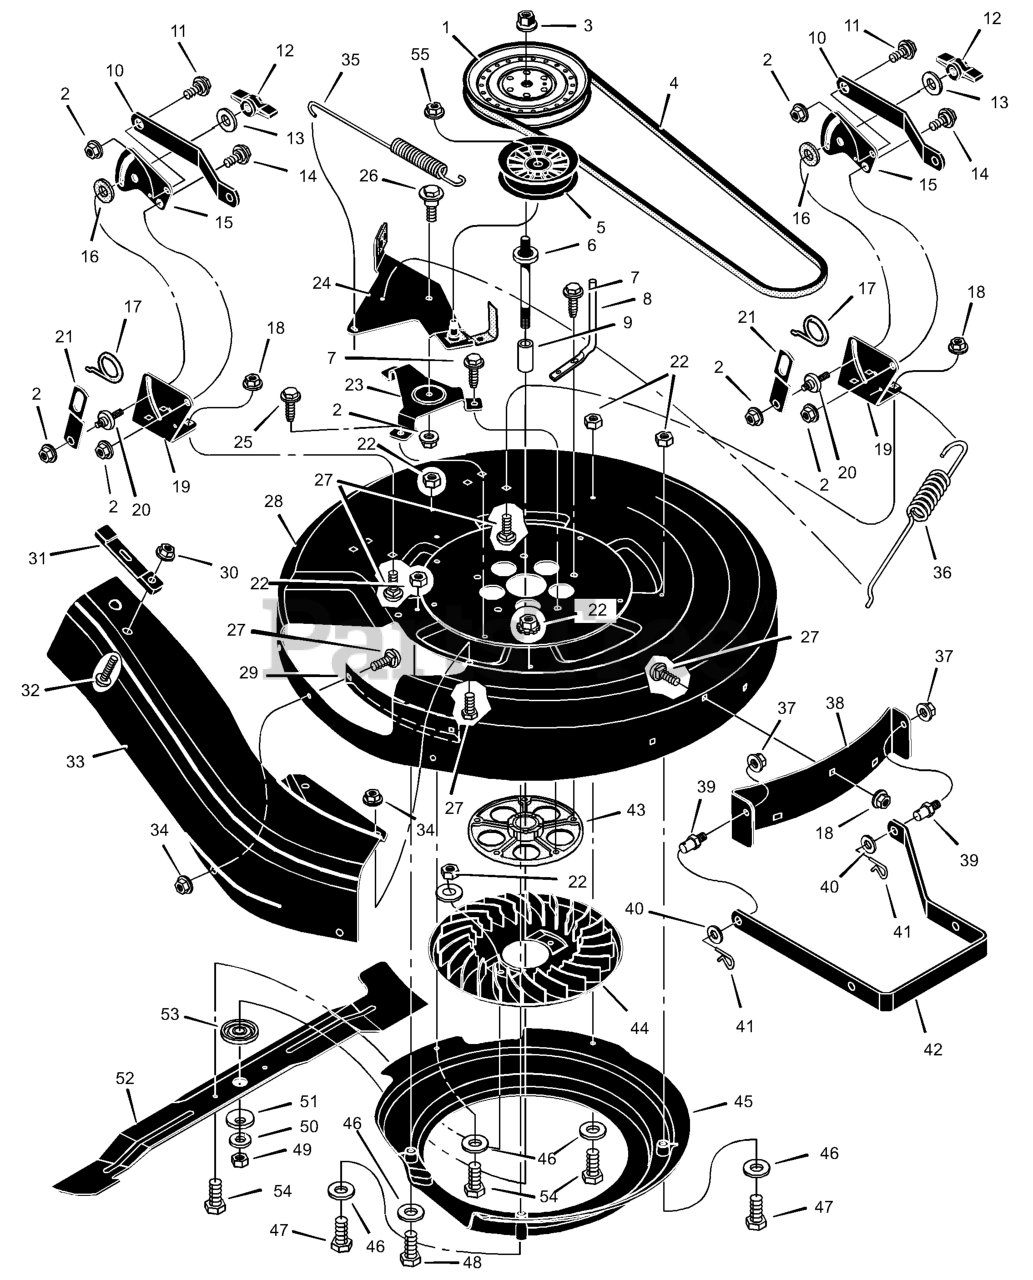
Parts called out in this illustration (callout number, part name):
2	Nut, Flange
4	Belt, Blade
5	Pulley, Idler
6	Mandrel
7	Screw
8	Guide, Belt
10	Bracket, Rear Suspension
11	Bolt, Shoulder
12	Knob
14	Bolt, Shoulder
15	Plate, Suspension
16	Pad, Friction
18	Nut, Flange
19	Bracket, Rear Deck
20	Pin, Hanger
21	Link, Lift
22	Nut
23	Bracket, Idler Arm
24	Assembly, Idler Arm & Pad
26	Bolt, Shoulder
27	Bolt, Carriage
28	Housing, Blade
30	Nut, Flange
31	Strap, Rubber
32	Screw
33	Extension, Chute
34	Nut
35	Spring, PTO
36	Spring, Extension
37	Nut, Flange
38	Bracket, Front Deck
39	Pin, Threaded Shoulder
41	Pin, Hair
42	Hanger, Front
43	Housing, Jackshaft
44	Fan, Assist
45	SCREW
46	Washer
48	Bolt
51	Washer, Belleville
52	Blade
53	Adapter, Blade
55	Nut, Flange
